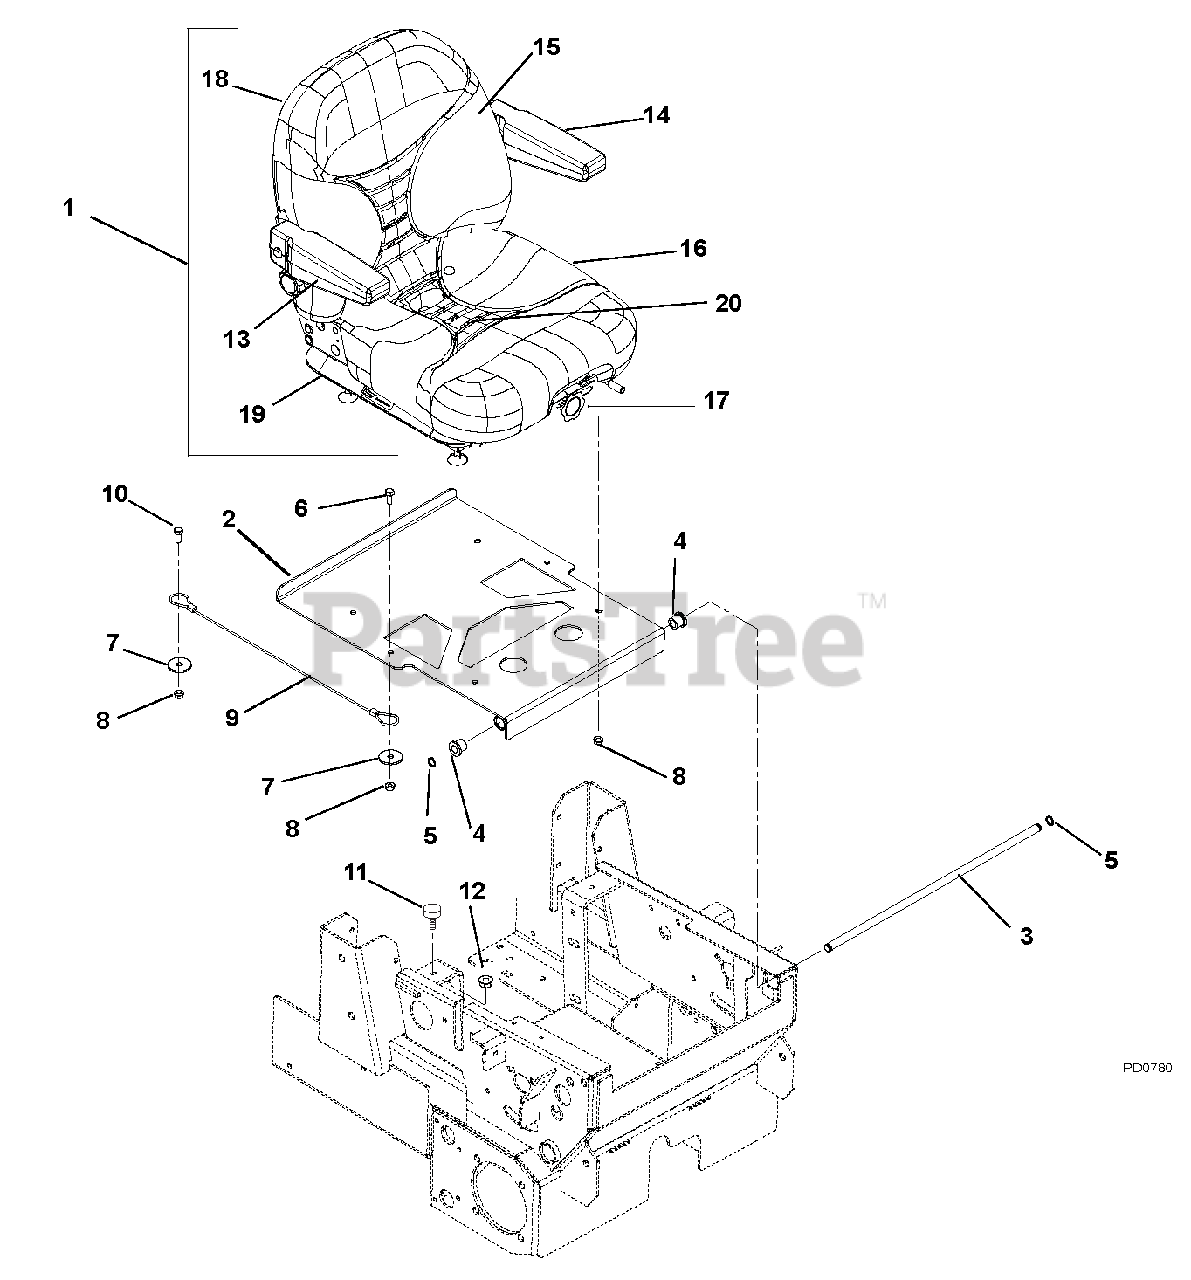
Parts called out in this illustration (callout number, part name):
1	SEAT-SUSP-LT GRY-SEAT BLT BUSH
2	WMT, SEAT PIVOT PLATE
3	ROD, SEAT PIVOT (OUTFRONT)
4	BSHG-FLG .515X.750X.745X1.00NY
5	RG-RTNG-EXT .500X.050 (SNAP)
6	@BLT-HEX .31-18X.75 GR5 YWZC
7	WSHR-FL-STL .344X1.125X.135
8	@NUT-LK-NYL-FLG .31-18 YWZC
9	CABLE, SEAT PROP.
10	@BLT-RDHDSQNK .31-18X1.00 G5YZ
11	BUMPER, RUBBER
12	NUT-SPNLK-FLG .312-18 YWZC
13	KIT-RH ARMREST ASSEMBLY REPLAC
14	KIT-LH ARMREST ASSEMBLY REPLAC
15	KIT-BACK CUSHION-LIGHT GRAY
16	KIT-SEAT CUSHION-LIGHT GRAY
17	KIT-SEAT KNOB
18	KIT-SEAT BACK PANEL
19	KIT-SEAT SLIDE
20	KIT-SPRING AND SADDLE
